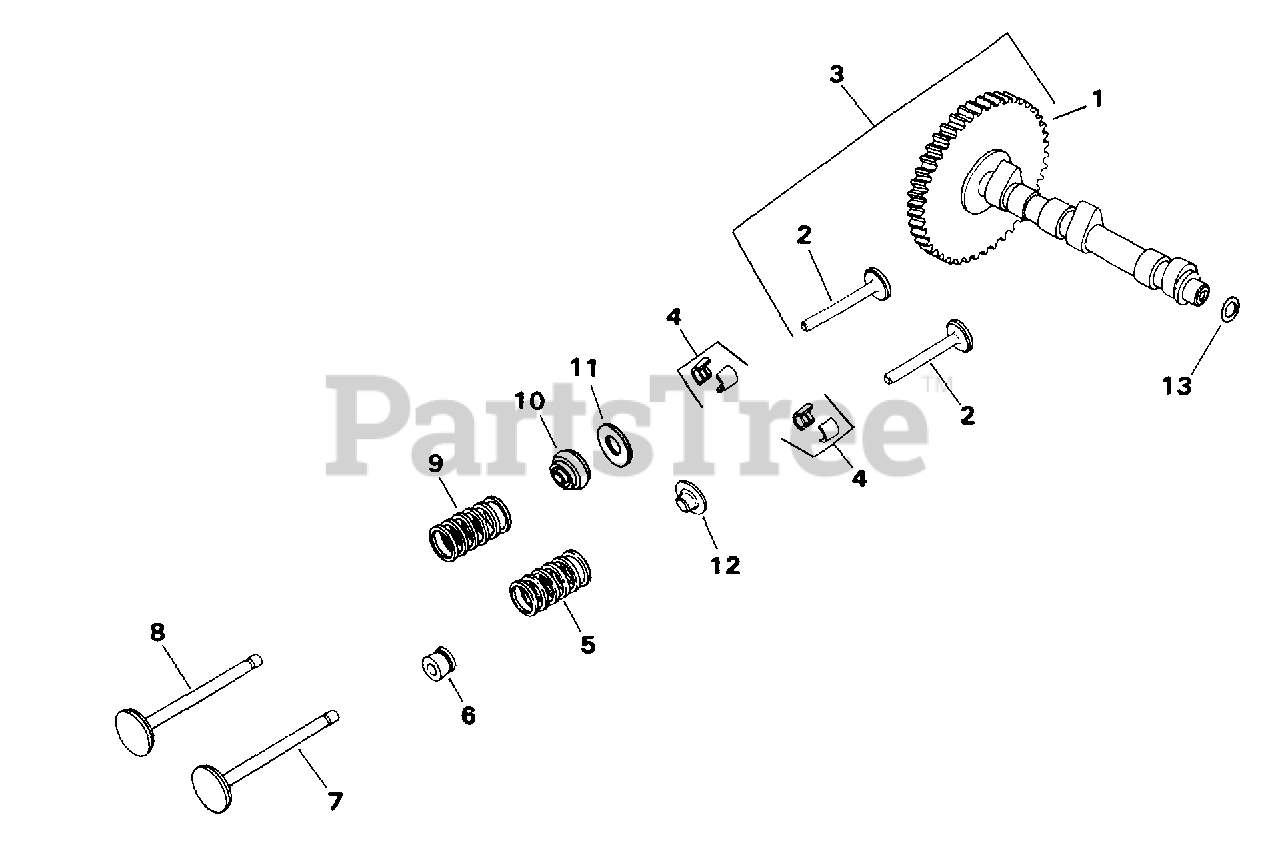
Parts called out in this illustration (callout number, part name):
3	KIT, CAMSHAFT - DISCONTINUED
4	KIT, RETAINER
7	VALVE - DISCONTINUED
8	KIT, VALVE - (#DSC)
12	RETAINER, VALVE SPRING
